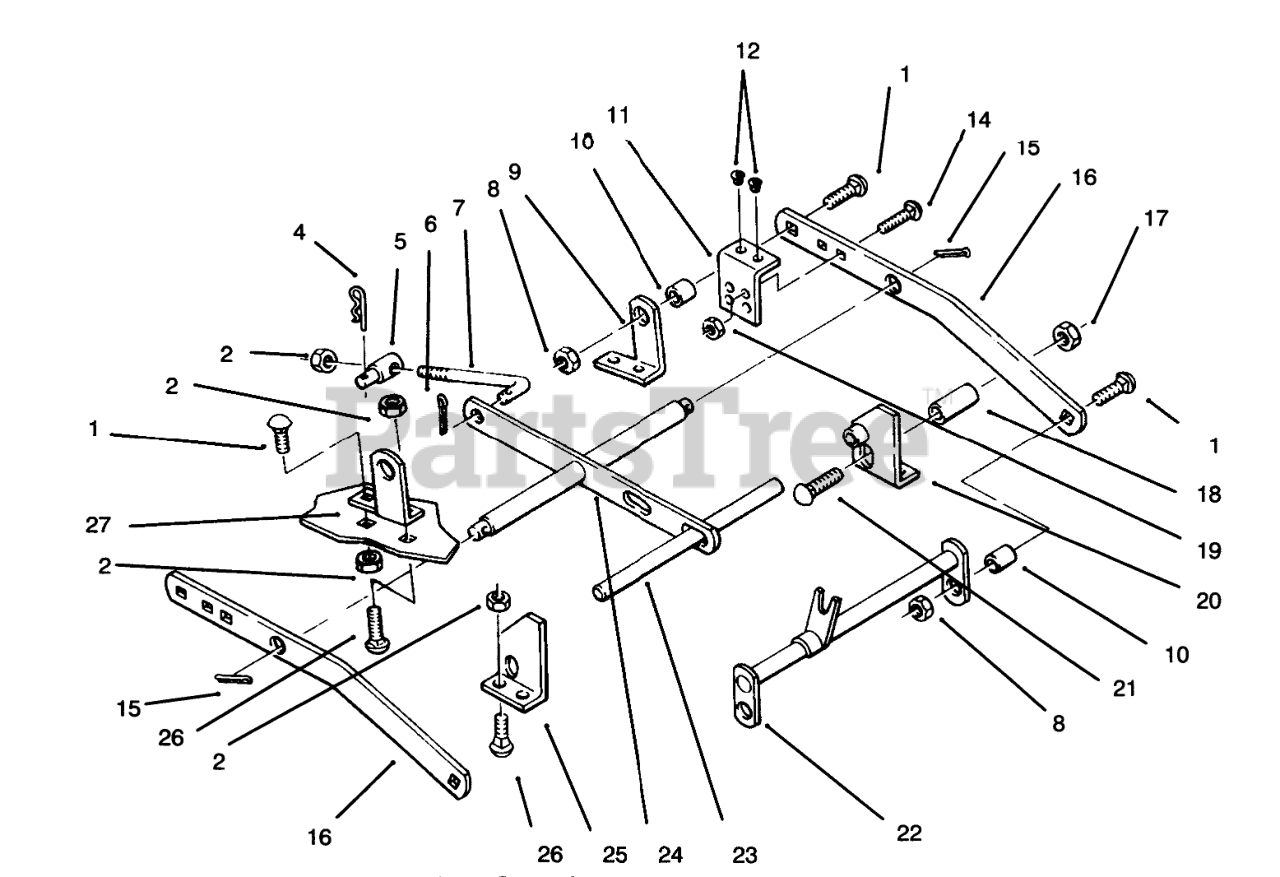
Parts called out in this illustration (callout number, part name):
1	BOLT-CARR
2	NUT-LOCK, NI
4	PIN-HAIR
5	TRUNNION-LIFT
6	PIN-COTTER
7	ROD-LEVEL ADJUST
8	LOCKNUT-FLANGE
9	LH Rear Bracket
10	SPACER
11	Bumper-Metal
12	BUMPER-RUBBER
14	BOLT-CARR
15	PIN-COTTER
16	Bar Draft
17	NUT-LOCK, NI
18	SPACER
19	NUT-LOCK, NI
20	Front Bracket LH
21	BOLT-CARR
22	Hitch
23	Front Shaft
24	Leveler
25	Front Bracket RH
26	BOLT-CARR
27	Rear Bracket RH
